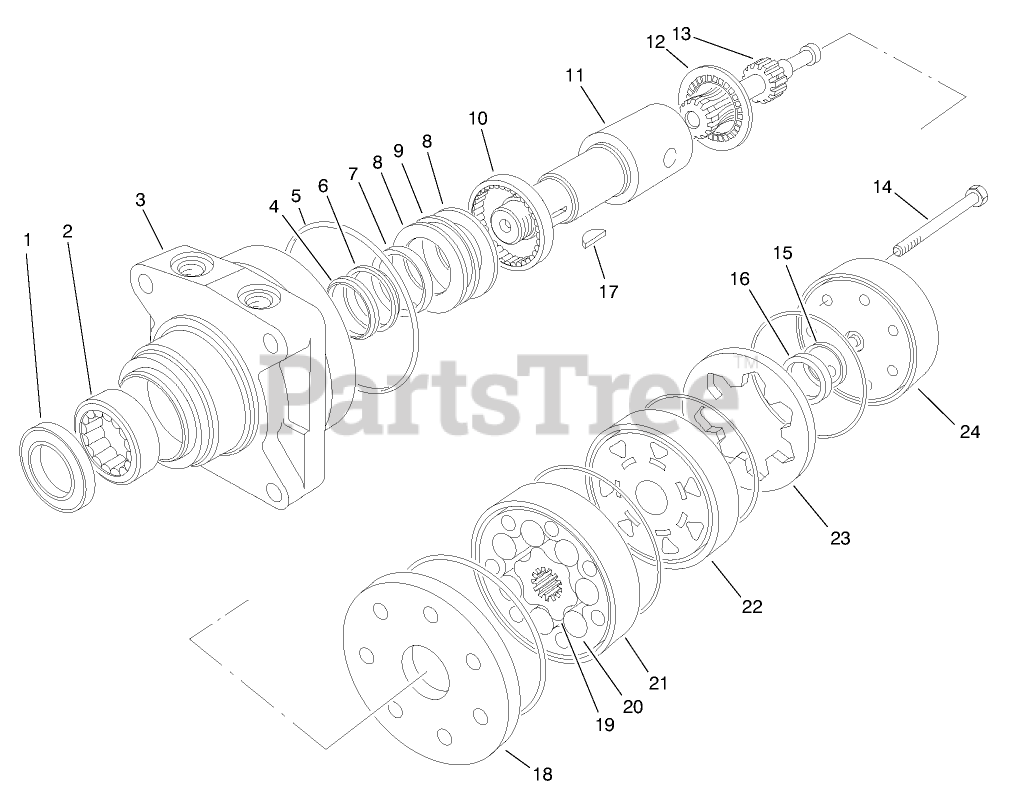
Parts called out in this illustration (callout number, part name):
4	Washer
11	SHAFT-COUPLING
13	Link-Drive
14	SCREW-CAP, HH
17	KEY-WOODRUFF
18	Plate-Wear
22	Manifold
24	End Cover Assembly
